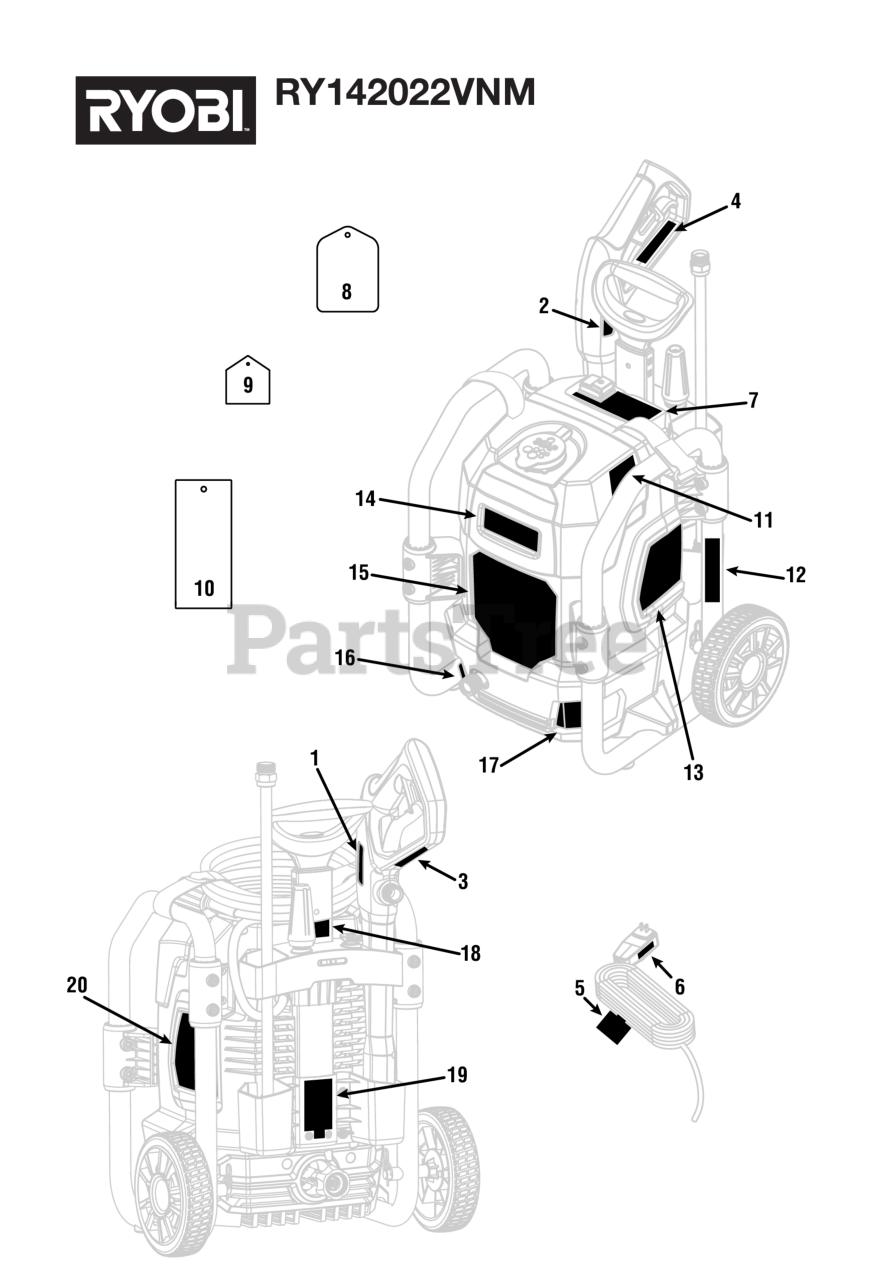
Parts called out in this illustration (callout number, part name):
1	Trigger Handle Label (Logo Label)
2	Trigger Handle Warning Label (English)
3	Trigger Handle Data Label
4	Trigger Handle Warning Label (French/Spanish)
5	Warning Label (Cord Wrap)
6	Power Cord Label
7	Starting Instructions and On/Off Label
8	Nozzle Hangtag (PS141913)
9	Hang Tag, Echo Prop 65
10	Danger Hangtag (Spanish)
11	Detergent Tank Label
12	Inquires Label (Ryobi)
13	Icons/EN Warnings Label
14	Logo Label
15	Performance Label
16	Left Side Vent Label
17	Right Side Vent Label
18	Soap Instructions Label
19	Data Label
20	Icons/FR Warnings Label
